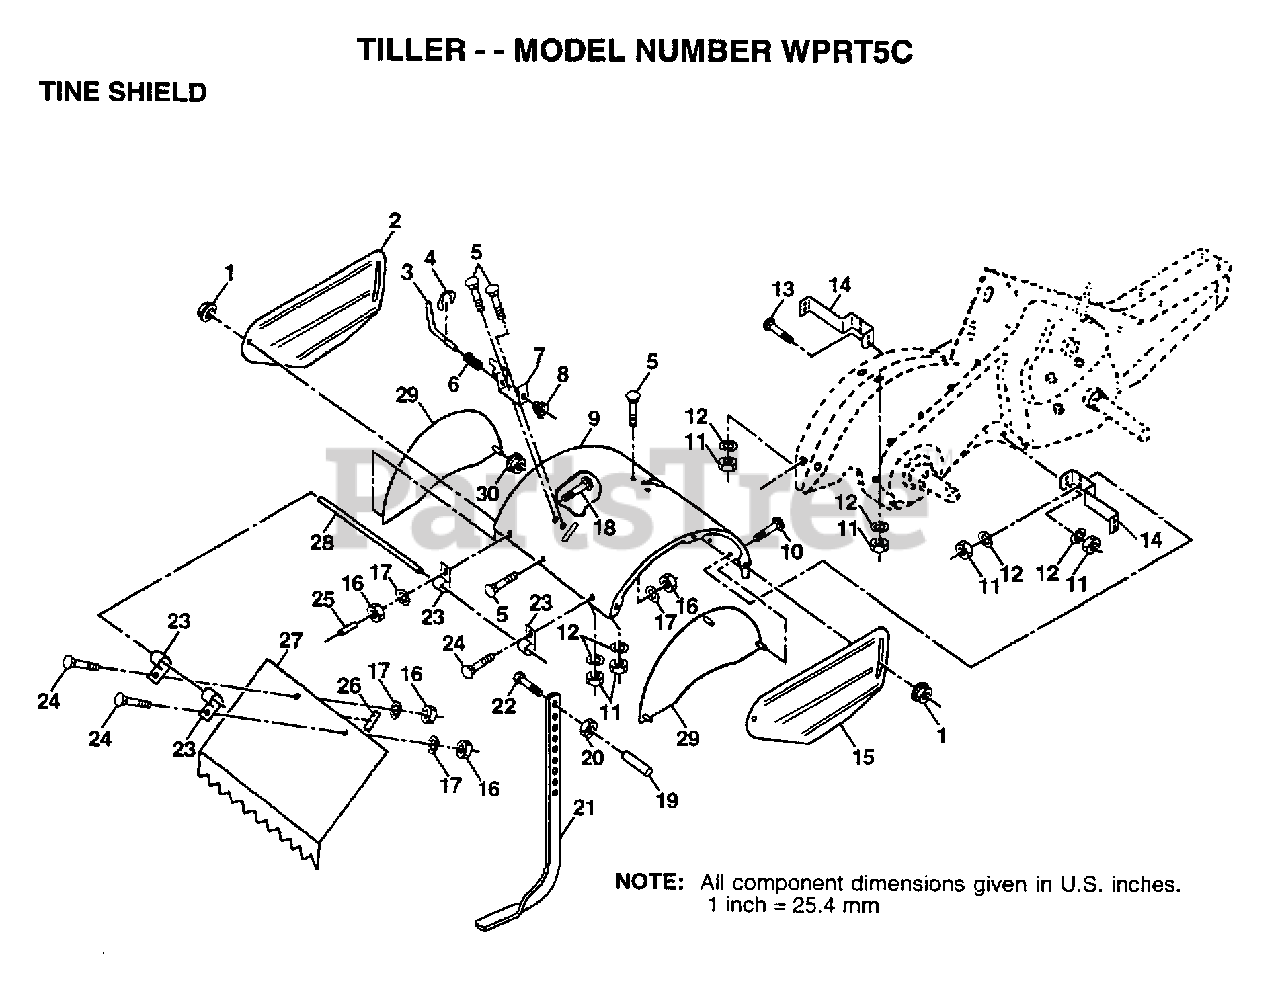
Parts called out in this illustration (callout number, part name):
1	NUT
2	SHIELD.SD.OUT.LH
3	STAKE PIN TI
4	KLIP RING TI
5	BOLT
6	SPRING TI
7	LATCH BRACKET TI
8	SPRING CRT
9	TINE SHIELD
10	BOLT
11	NUT.HEX.5/16-18
12	LOCKWASHER
13	BOLT
14	"BRACKET,SHIELD"
15	SHIELD.SD.OUT.RH
17	LOCKWASHER
18	BOLT
19	GRIP CRT
20	NUT.HEX.3/8-16UNC
21	STAKE DEPTH 16
22	BOLT
23	HINGE CRT
24	BOLT
25	VINYL CAP TI
26	PAD IDLER TI
27	LEVELING SHIELD
28	PIN HINGE
29	SIDE SHIELD
30	LOCKNUT TI
